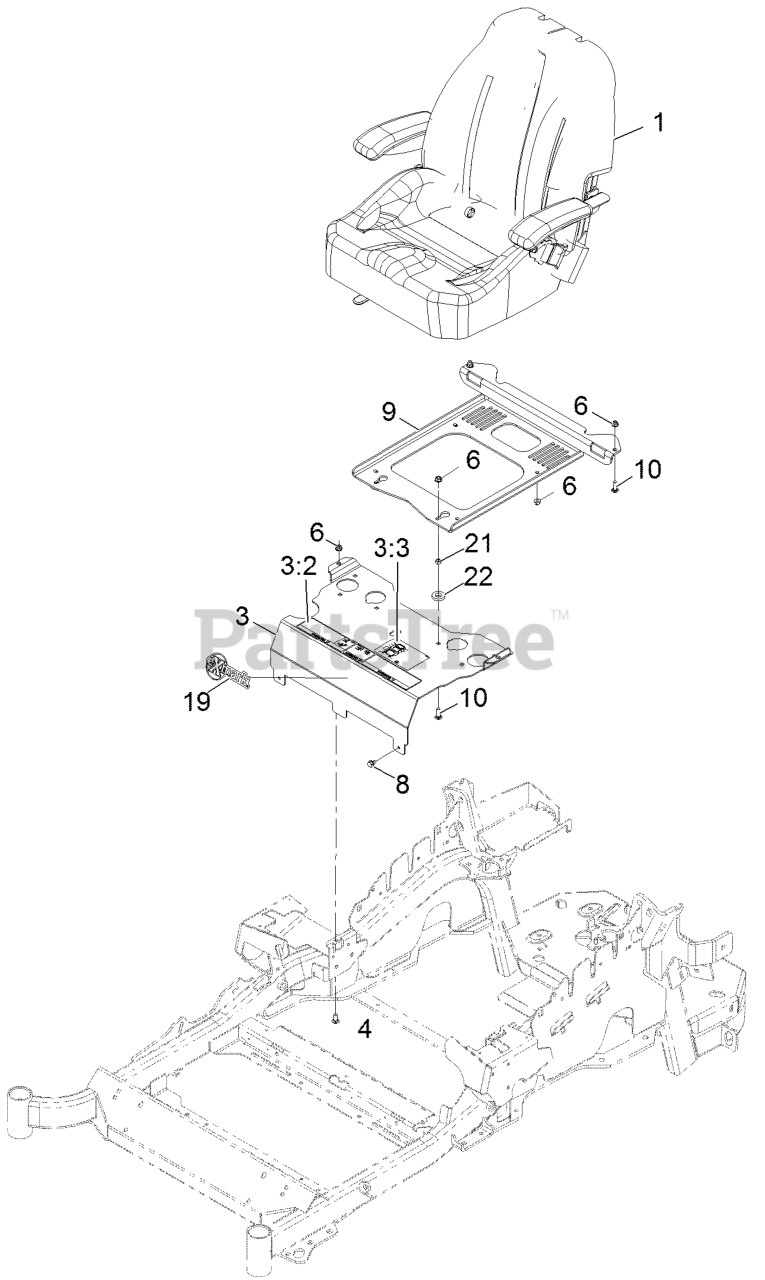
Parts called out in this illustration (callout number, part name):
1	ASM-SEAT LZE
3	MOUNT-SEAT
3:2	DECAL-CONSOLE
3:3	DECAL-SERVICE AID
4	SCREW-CARR
6	NUT-HF, NI
9	PLATE-SUPPORT, SEAT
10	SCREW-CARR
21	NUT-HEX
